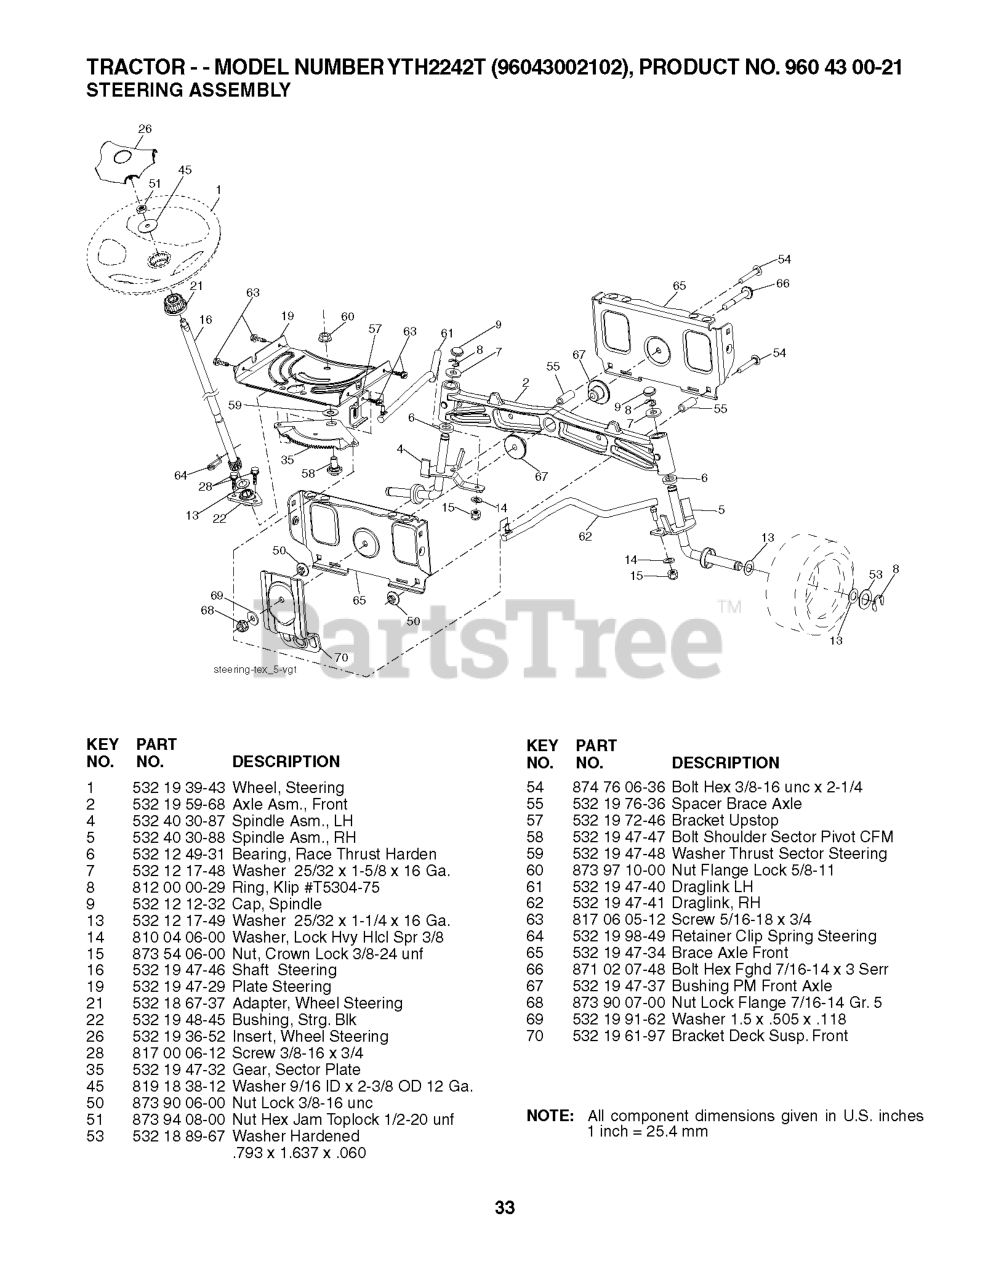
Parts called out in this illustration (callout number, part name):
1	WHEEL.STEERING.LEGEND2.GRY
2	AXLE.CAST.IRON
4	SPINDLE.WELDED.LH.15"TEX
5	SPINDLE.WELDED.RH.15"T
6	THRUST WASHER
9	CAP.SPINDLE.BLACK
14	WASHER, LOCK 3/8
15	NUT CROWNLOCK 3/8-24
16	SHAFT.STEER.STEALTH.DD
19	PLATE.STEER.DDL.NLT/NG
21	ADAPTER, WHEEL STNG..
22	BUSHING.ASM.STEERING.A
26	INSERT.CAP.STRG.WH.GRAY
28	SCREW, 3/8-16X3/4
35	GEAR.SECTOR.PLATE.DDL.
45	WASHER 9/16"ID, 2 3/8"OD
50	NUT LOCK FLG 3/8-16 UNC
51	NUT.HEX.1/2-20
53	WASHER.HARDENED
55	SPACER.BRACE.AXLE (2 2)
57	BRKT.UPSTOP.GT/LT.TEX
58	BOLT.SHOULDER.SECTOR.P
59	WASHER.THURST.SECTOR.S
60	NUT FLANGE LOCK 5/8-11
61	DRAGLINK.LH.BALLSTUD.D
62	DRAGLINK.RH.BALLSTUD.D
63	SCREW 5/16"
64	RETAINER.CLIP.SPRING.S
65	BRACE.AXLE.FRONT.NLT/N
66	BOLT HEX FGHD 7/16-14 X 3 SERR
67	BUSHING.PM.FRONT AXLE
68	NUT.LOCK.FLANGE.7/16
69	WASHER.1.5X.505X.118
70	BRKT.DECK.SUSPENSION.F
